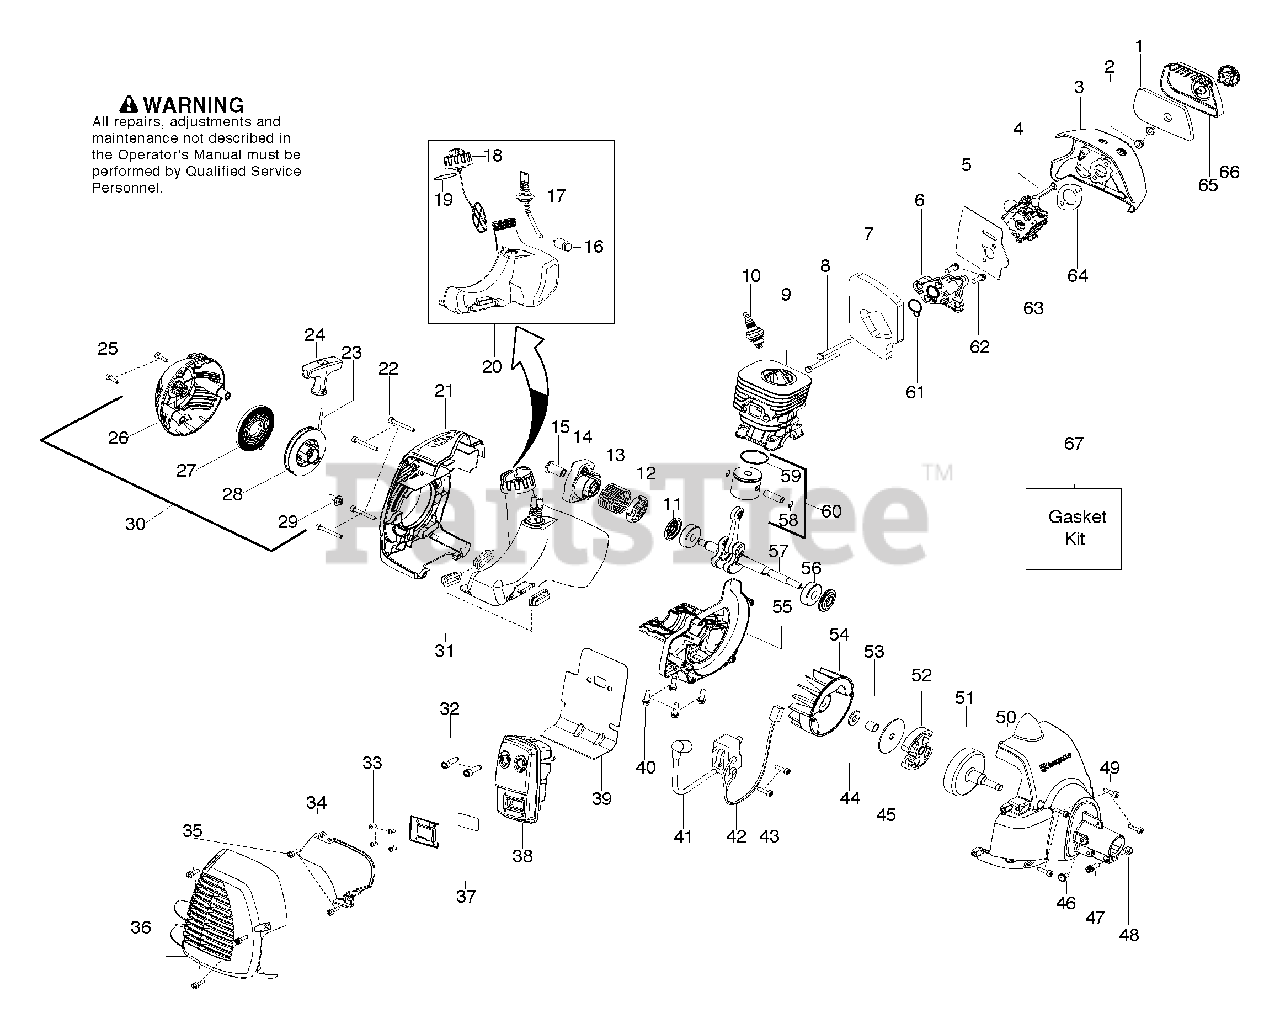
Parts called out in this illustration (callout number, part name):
2	Nut-Carb. Screw
3	Air Box
4	Lever-Choke
5	Kit-Carb. Gasket
6	Adaptor-Carb.
7	Kit-Gasket (foam)
9	Cylinder
10	Plug-Spark (RCJ-8Y)
11	Kit-Crankshaft seal
12	Washer-Starter
13	Spring-Starter Cup
14	Assy-Starter Cup
15	Coupling-Starter
16	Assy-Fuel Filter
17	Kit-Fuel Line
18	Assy-Cap w/ret.
19	O-ring - Fuel Cap
20	Assy-Fuel Tank
21	Shroud-Rear
24	Handle-Starter
26	Starter Hsg. w/eyelet
27	Kit-Starter Spring
28	Kit-Starter Pulley
30	Assy-Starter Hsg.
31	Isolator-Tank
32	Bolt-Muffler
34	Shield-Heat
36	Guard-Muffler
37	Kit-Spark Arrestor
38	Assy-Muffler
39	Gasket-Paper Metal
42	Assy-Leadwire
45	Washer-Clutch
50	Assy-Fan Housing
51	Assy-Clutch Drum
52	Kit-Clutch Assy.
57	Kit-Crankshaft
58	Retainer-Piston Pin
59	Ring-Piston
60	Kit-Piston
61	Kit-Gasket (adaptor seal)
63	Kit-Carb.
64	Kit-Gasket (air box)
65	Cover-Air Box
67	Kit-Gasket
